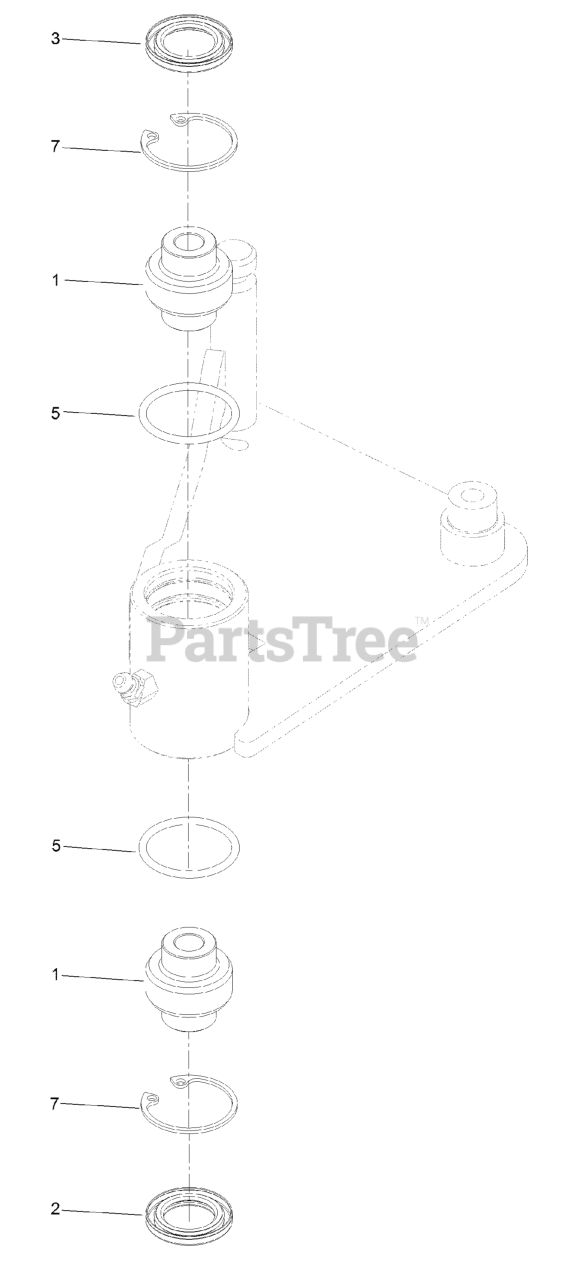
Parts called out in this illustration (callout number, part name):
1	BEARING-SPHERICAL
2	SEAL-LIP, DOUBLE
3	SEAL-LIP, SINGLE
7	RING-SNAP
